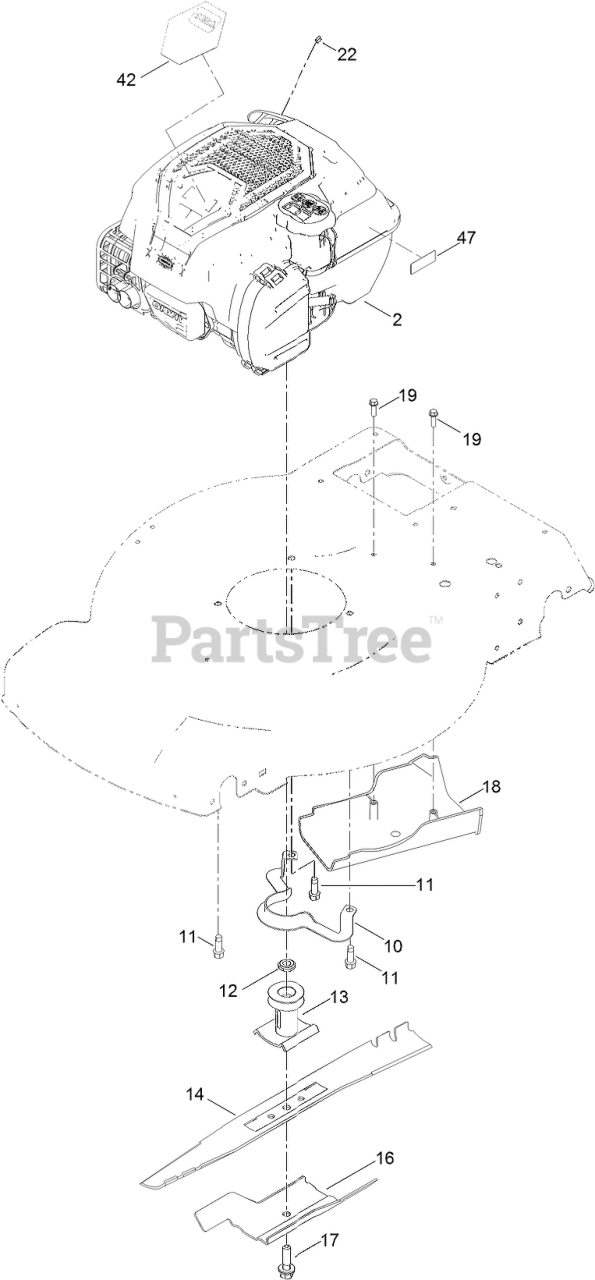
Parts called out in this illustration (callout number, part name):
10	GUIDE-BELT
11	SCREW-TAPTITE
12	SPACER-DRIVER
13	DRIVER-BLADE
16	ACCELERATOR-BLADE
17	BOLT-BLADE
18	COVER-BELT
19	SCREW-HWH
22	STOP-ROPE
42	DECAL-SHROUD
47	DECAL-LEVEL, FUEL
